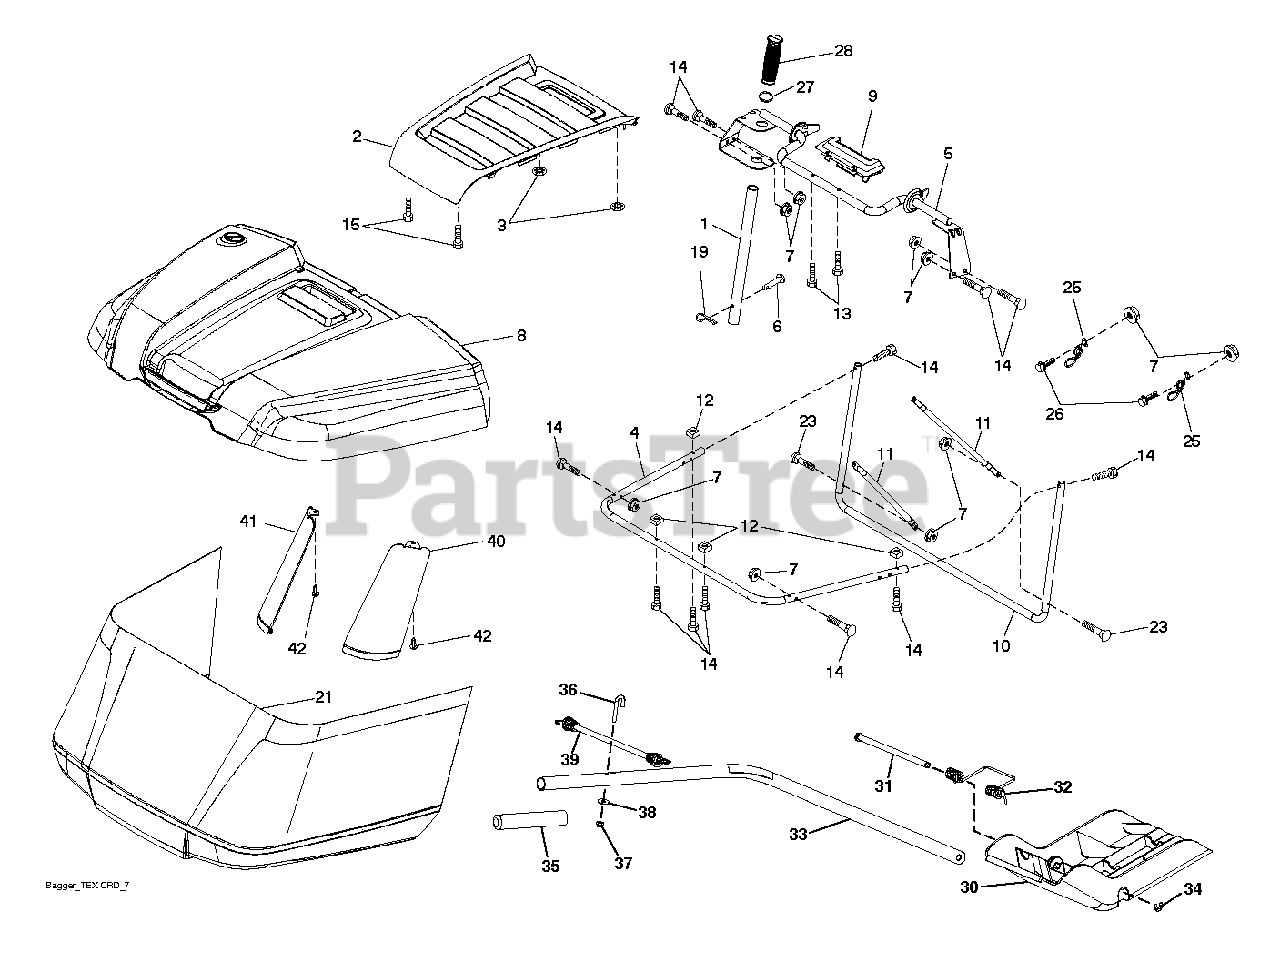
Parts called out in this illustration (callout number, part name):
1	TUBE.HANDLE.BAGGER.CRD/SRD.BLA
2	APPLIQUE.TOP.BAG.SRD.ORANGE
3	NUT.PUSH.156
4	SUBASM.TOP.TUBE.TEX.CRD
5	FRAME.ASM.TOP.BAGGER.SRD
6	RIVET,DRILLED
7	NUT T
8	BAGGER.TOP.SRD.APPLIQUE
9	INSERT.HANDLE.BAGGER.(2 2)
10	FRAME FRAME.FRONT.TEX.CRD
11	BRACE BRACE SIDE TUBE
12	NUT.SQUARE.1/4
13	SCREW.1/4X1.150.HXWSH
14	BOLT.SHOULDER.HX.WSH.1/4X1.150
15	SCREW,#8.FLAT.HEAD.DRILL.TIP
19	PIN.COTTER.5/16.BOW TI
25	SPRING.LATCH.BAGGER.SRD
26	SCREW HEX CRT
27	RB GROMMET.RUBBER.SRD
28	GRIP.HANDLE.BLACK
30	PLUG PLUG
31	PIN PIN.HINGE
32	SPRING SPRING DOUBLE TORSION
33	SHAFT SHAFT TEX CRD MULCH PLU
34	E-RING.5/16"
35	GRIP GRIP MULCH PLUG HAND
36	BOLT BOLT J
39	BUBGEE BUBGEE TEX CRD
42	CLIP CHRISTMAS TREE CLIP
